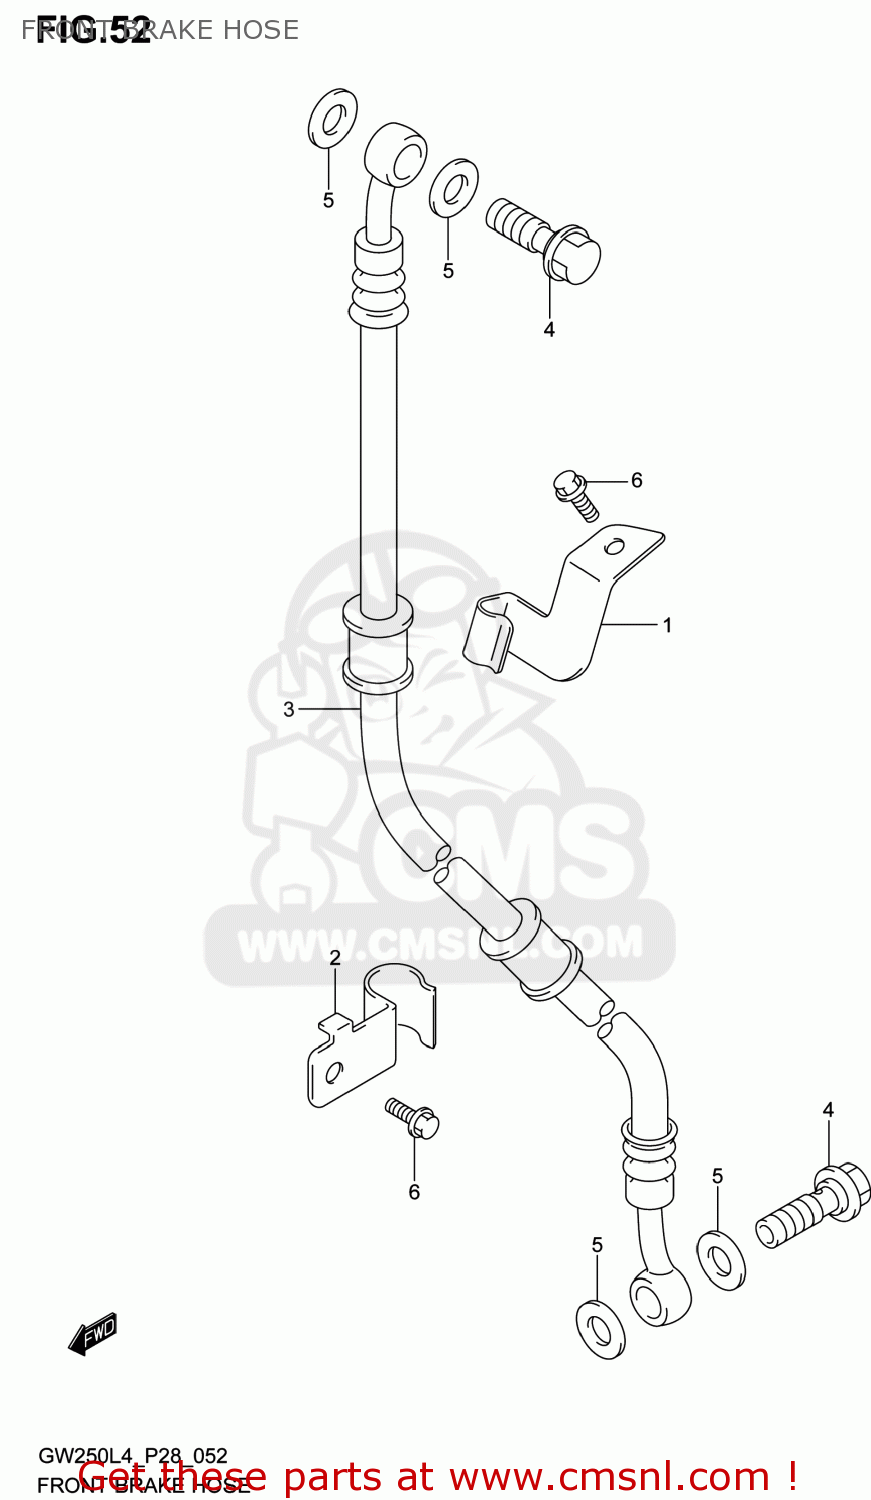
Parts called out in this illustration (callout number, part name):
1	CLAMP,FR BRAKE HOSE NO.1
2	CLAMP,FR BRAKE HOSE NO.2
3	HOSE,FR BRAKE
4	BOLT,BRAKE FLUID
5	WASHER,BRAKE FLUID
6	BOLT
